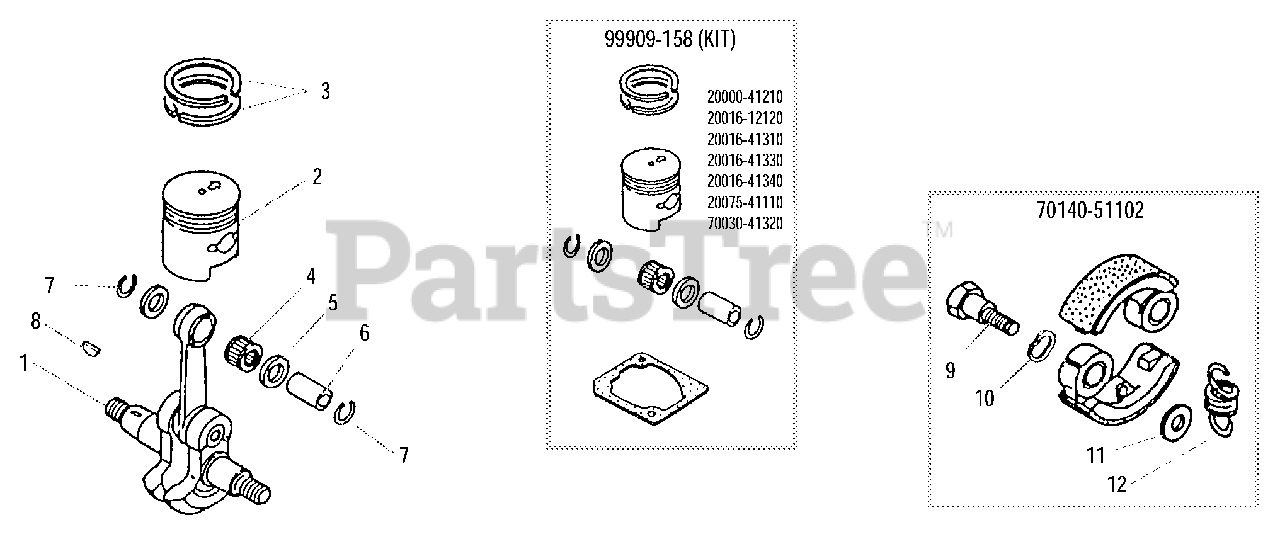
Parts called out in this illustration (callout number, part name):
1	CRANKSHAFT ASSY
2	PISTON
3	RING, PISTON
4	BEARING, NEEDLE
5	WASHER, THRUST
6	PIN, PISTON
7	RING, RETAINING
8	KEY - 3X10
9	BOLT, CLUTCH
10	WASHER - SPRING
11	WASHER - 6
12	SPRING, CLUTCH
20016-12120	GASKET, CYLINDER
70140-51102	CLUTCH ASSY
99909-158	PISTON ASSY
